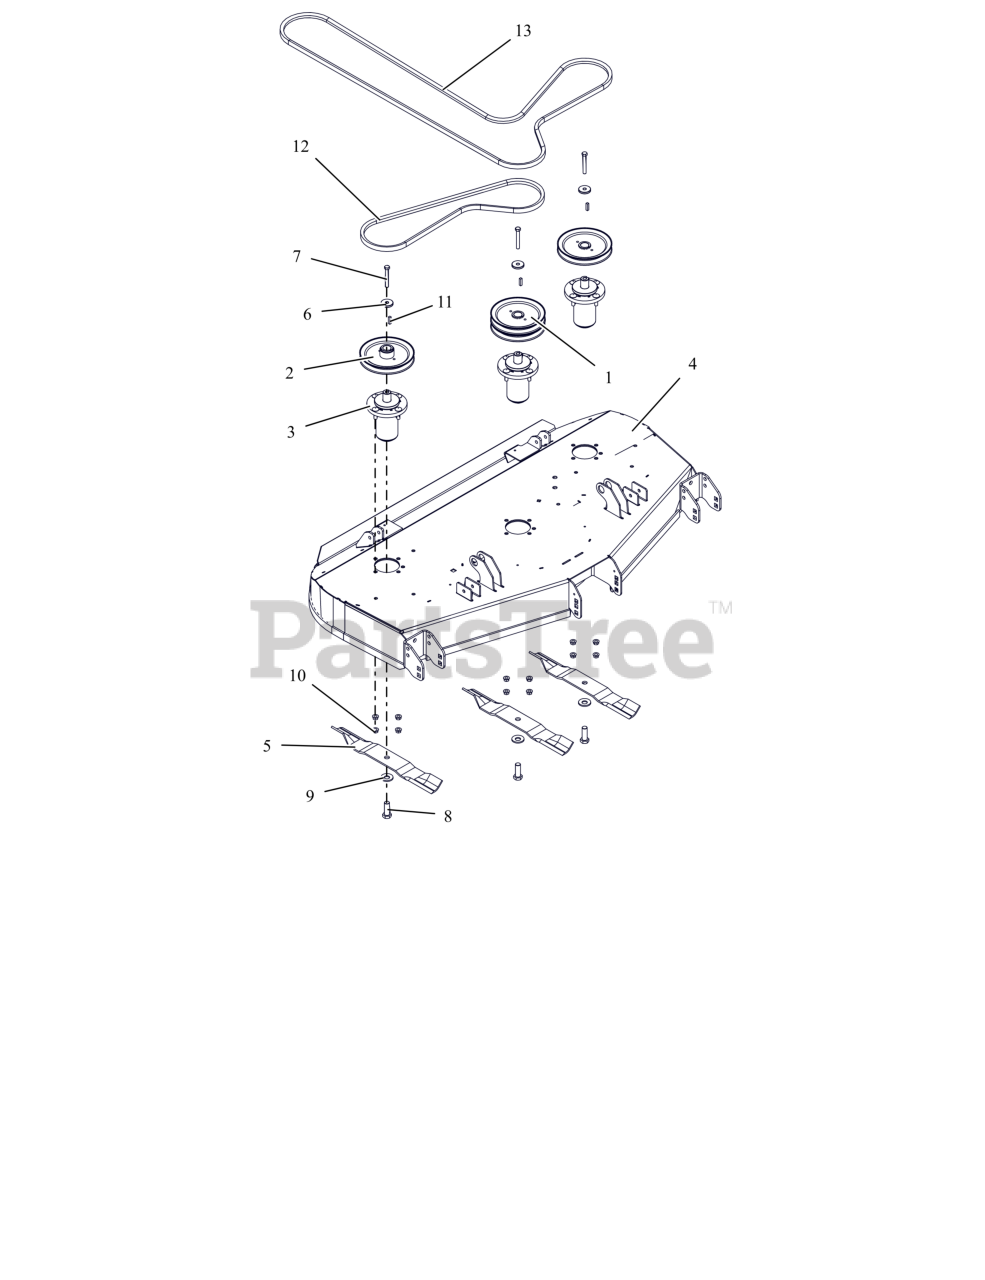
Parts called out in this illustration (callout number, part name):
1	PULLEY, DOUBLE 1.000 ID X 6.750 OD-BLACK
2	PULLEY, V-1.000 ID X 6.750 OD
3	ASM, MAINT FREE ALUM SPINDLE
4	WLDMT, DECK 52 RD (ORANGE)
5	BLADE, 18"
6	RETAINER, SHEAVE
7	BLT, HEX .38-16X2.75 G8 ZCC
8	BLT, HEX .62-18X1.75 G8 ZCC
9	WSHR-BLVL .669X1.535X.138
10	NUT-LK-CTR-FLG .375-16 GF ZCC
11	KEY, SQ .25X.25X1.00 RC 40-50
12	V-BELT, B-COGGED
13	V-BELT, HB SECTION
